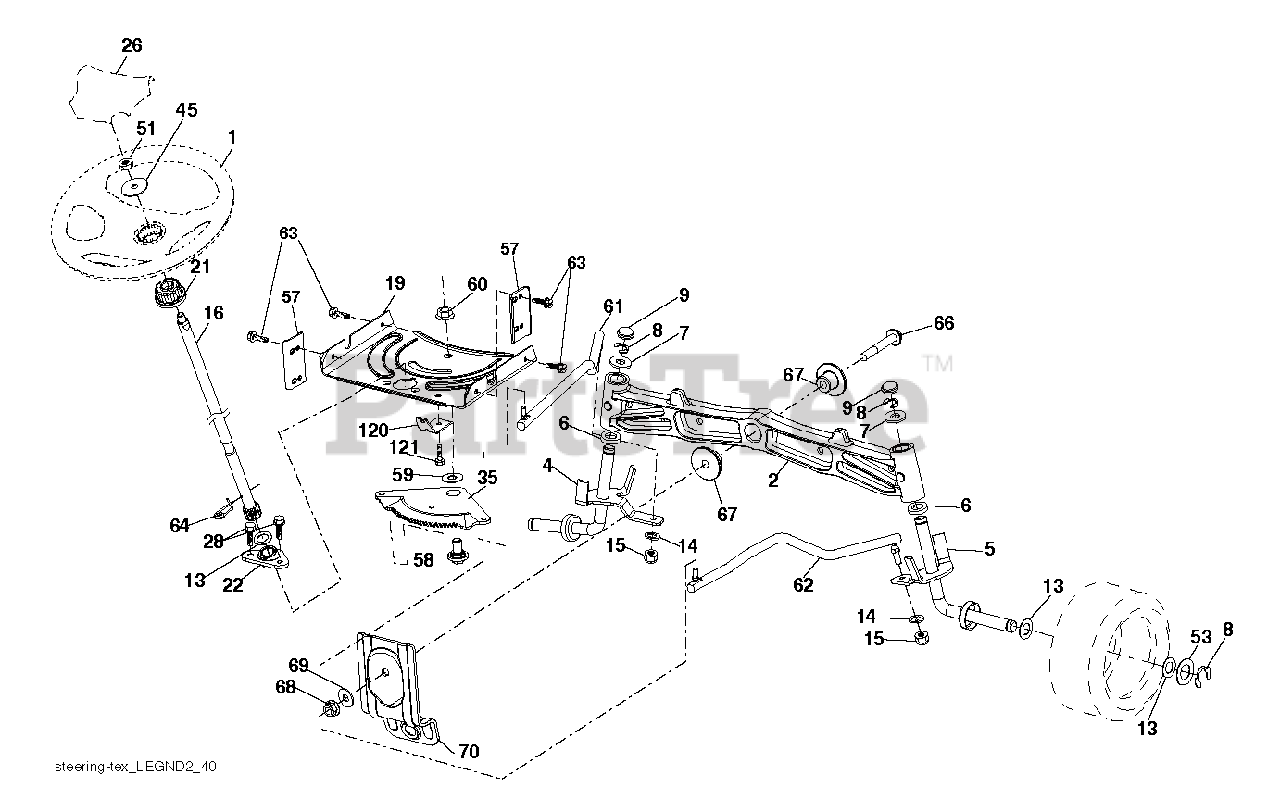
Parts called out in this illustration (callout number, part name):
1	WHEEL.STEERING.HUSQ.PREM.HRDRM
2	AXLE.CAST.IRON
4	SPINDLE.WELDED.LH.15"TEX
5	SPINDLE.WELDED.RH.15"T
6	THRUST WASHER
9	CAP.SPINDLE.BLACK
14	WASHER, LOCK 3/8
15	NUT CROWNLOCK 3/8-24
16	SHAFT, STEERING
19	PLATE.STEER.DDL.NLT/NG
21	ADAPTER, WHEEL STNG..
22	STEERING.SUPT.LOWER.
26	INSERT.CAP.WHL.STRG.HUSQ.PREM
28	SCREW, 3/8-16X3/4
35	GEAR.SECTOR.PLATE.DDL.
45	WASHER 9/16"ID, 2 3/8"OD
51	NUT.HEX.1/2-20
53	WASHER.HARDENED
57	BRACKET.UPSTOP.TEX
58	BOLT.SHOULDER.SECTOR.P
59	WASHER.THURST.SECTOR.S
60	NUT FLANGE LOCK 5/8-11
61	DRAGLINK.LH.BALLSTUD.D
62	DRAGLINK.RH.BALLSTUD.D
63	SCREW
64	RETAINER.CLIP.SPRING.S
66	BOLT HEX FGHD 7/16-14 X 3 SERR
67	BUSHING.PM.FRONT AXLE
68	NUT.LOCK.FLANGE.7/16
69	WASHER.1.5X.505X.118
70	BRKT.DECK.SUSPENSION.F
120	BRKT.LOCATOR.CBL.BRAKE.VARIATO
121	SCREW LT
